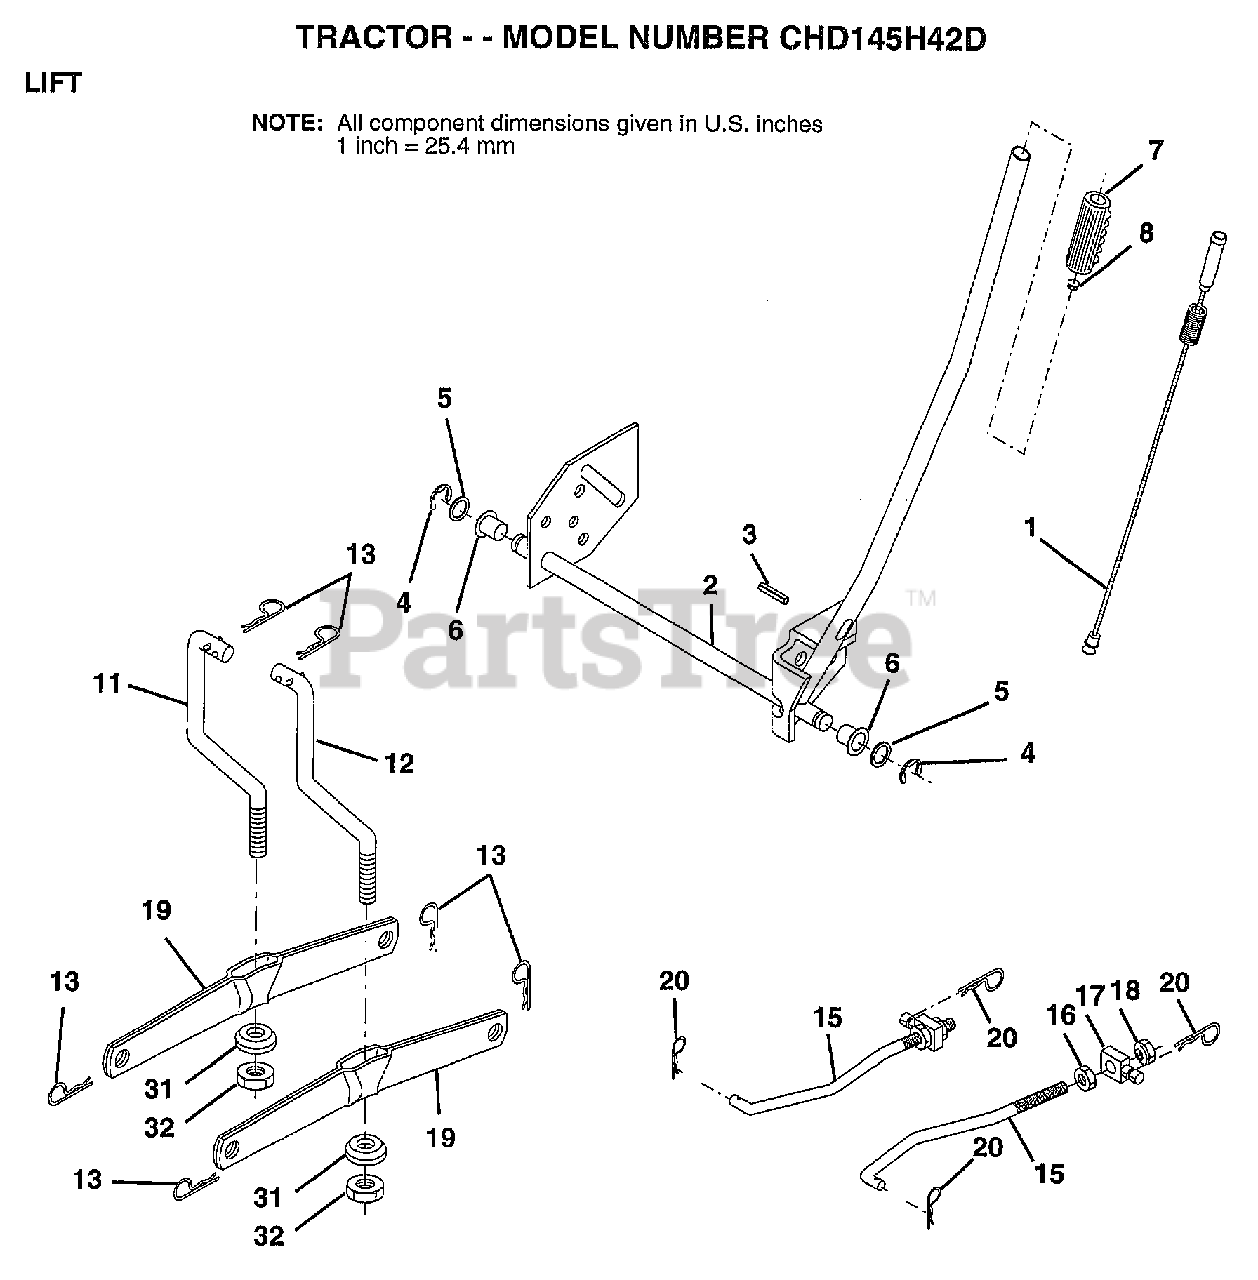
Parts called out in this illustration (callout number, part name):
1	WIRE ASM W.SPRING
2	"SHAFT ASM LIFT,RH"
3	PIN-GROOVE LT
5	WASHER
6	NYLON BEARING
7	GRIP
15	LINK.FRONT
16	NUT
17	TRUNION
18	NUT LTV
19	ARM SUSP REAR
20	RETAINER SPRING
31	BEARING PVT LH
32	NUT.CROWNLOCK.3/8
